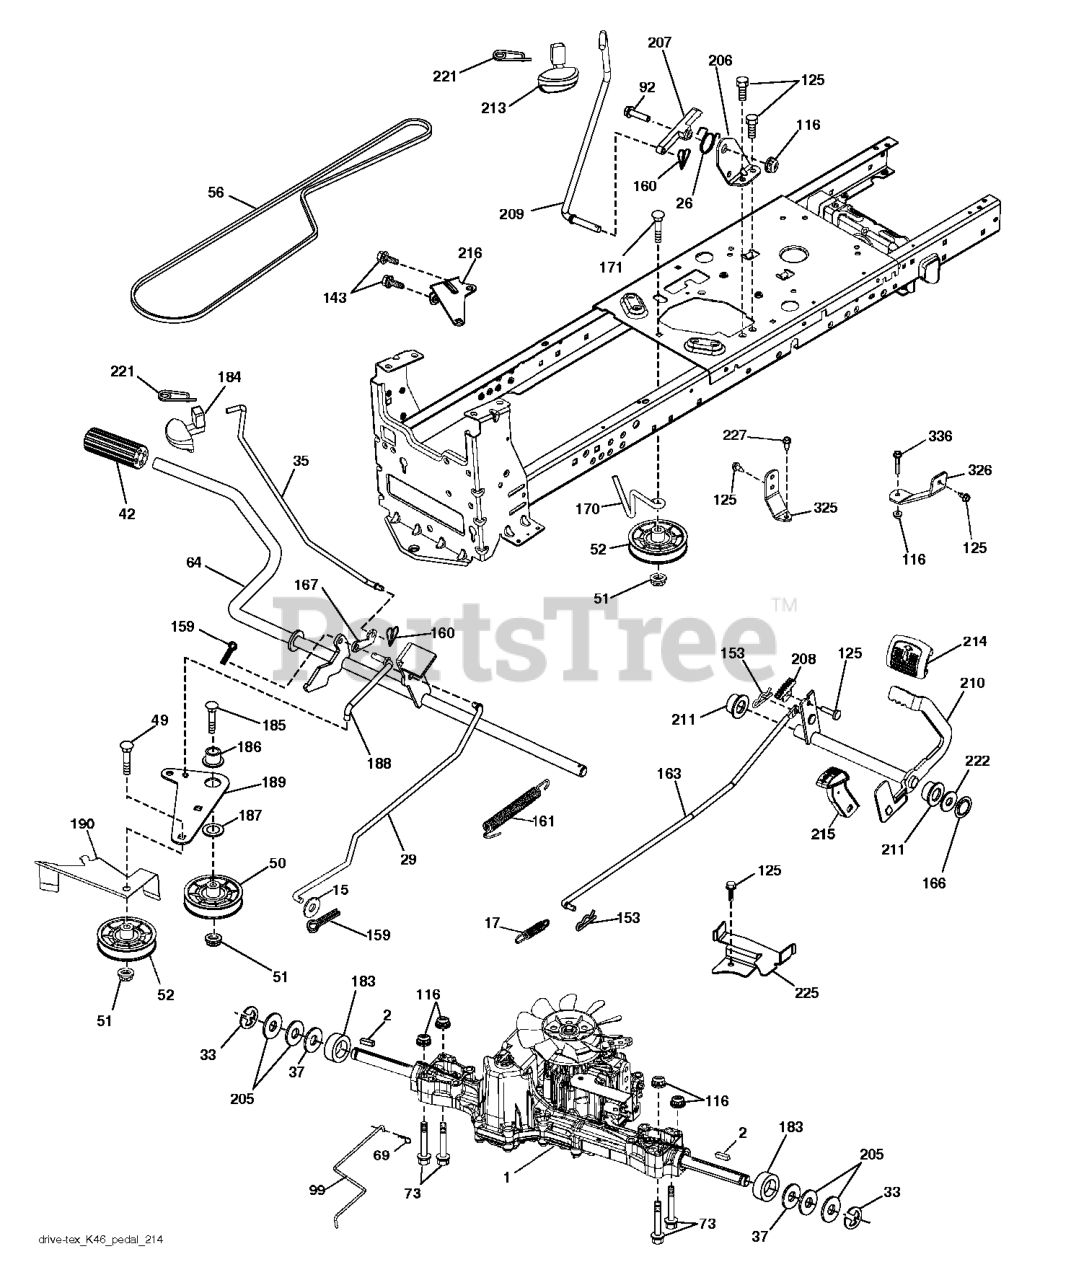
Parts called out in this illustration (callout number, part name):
2	SQUARE KEY
15	WASHER
17	SPRING.BRAKE.K46.GREEN
26	SPRING.RETURN.CRUISE
29	ROD.BRAKE.K46
35	ROD ROD.PARKINGBRAKE.GT.HUSQ/P
37	WASHER.HARDENED
42	PEDAL COVER T
50	IDLER.FLAT.910.OFFSET
51	NUT LOCK FLG 3/8-16 UNC
52	IDLER.V-GROOVE.910.OFFSET
56	V-BELT.MOWER.92.40.42/K46
64	SHAFT.ASM.PEDAL.BRK.CNTR
69	HAIRPIN.SOFT.ZINC.059X1.125
92	BOLT
99	ARM.PIVOTING.TCRD.GEN2.5.BAGGE
116	NUT LOCK HEX FLANGE 5/16-18
125	SCREW
143	SCR 5/16-18 X 1/2 SELFTAP ZN
153	RETAINER M
159	COTTER PIN
160	RETAINER CLIP
161	SPRING, RETURN LT
163	ROD.CONTROL.K57R.K46
166	NUT.PUSH.625
167	LATCH.BRAKE.SPRING
170	KEEPER.V-IDLER.CENTER.
183	SPACER AXLE
184	HANDLE.PARKING.BRAKE.H (BLK)
186	SPACER.RETAINER
187	WASHER 12/32X2X10GA
188	LINK.CLUTCH.GROUND DRIVE.LONG
189	BELLCRANK.GROUND.DRIVE.TEX.
190	KEEPER.BELLCRANK.DRIVE
206	BRACKET.MOUNT.CRUISE.LATCH
207	LATCH.CONTROL.CRUISE.TEX
208	GEAR.SECTOR.CONTROL.CR
209	ROD ROD.CRUISECONTROL.GT.HUSQ/
210	ROCKER.ASM.PEDAL.CONTR
211	BEARING.NYLON
213	KNOB.CONTROL.CRUSIE.HU
214	PEDAL.FORWARD.PAD.TEX
215	PEDAL.COVER.REVERSE.CRD.X428BK
216	BRACKET.PULLEY.IDLER.W/TEX
221	RETAINER.SPRING.CLIP.H
222	WASHER 21/32 X 1-1/4 X 10 GA.
225	KEEPER.BELT.TRANSAXLE.K46
227	SCREW.THDROL.5/16-18X3/4.TTY
325	BRACKET.TRQ.STP.46.20".TIRE.LH
326	BRCKT.PNT.TRQ.STP.46.20TIRE.RH
336	BOLT.5/16-18X1-3/4.FLANGED.HEX
